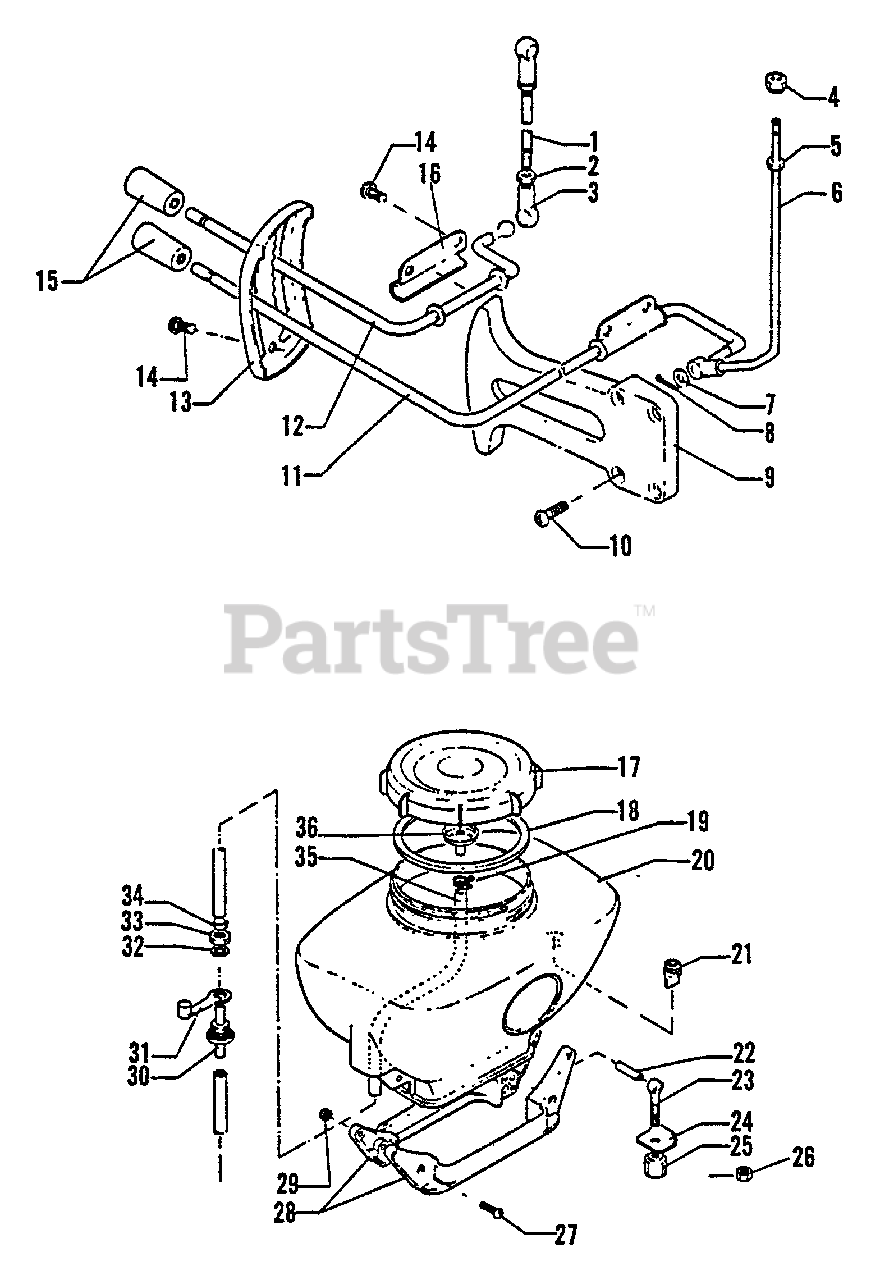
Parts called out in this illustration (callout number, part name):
1	ROD, DUST CONTROL
3	CONNECTOR
6	ROD, THROTTLE
7	WASHER - 4
9	BRACKET, DIAL
10	SCREW - 5X20
11	LEVER, THROTTLE
12	LEVER, DUST CONTROL
14	SCREW - 5X10
15	KNOB, THROTTLE CONTROL
16	RETAINER
17	CAP, CHEMICAL TANK
18	GASKET, CAP
19	CLAMP
20	TANK, CHEMICAL - 10 LITER
27	SCREW - 5X30
28	HOLDER
30	CONNECTOR, PIPE
32	WASHER - 12
33	NUT - 12
34	CLAMP
35	HOSE, FLUID
36	VENT, TANK
